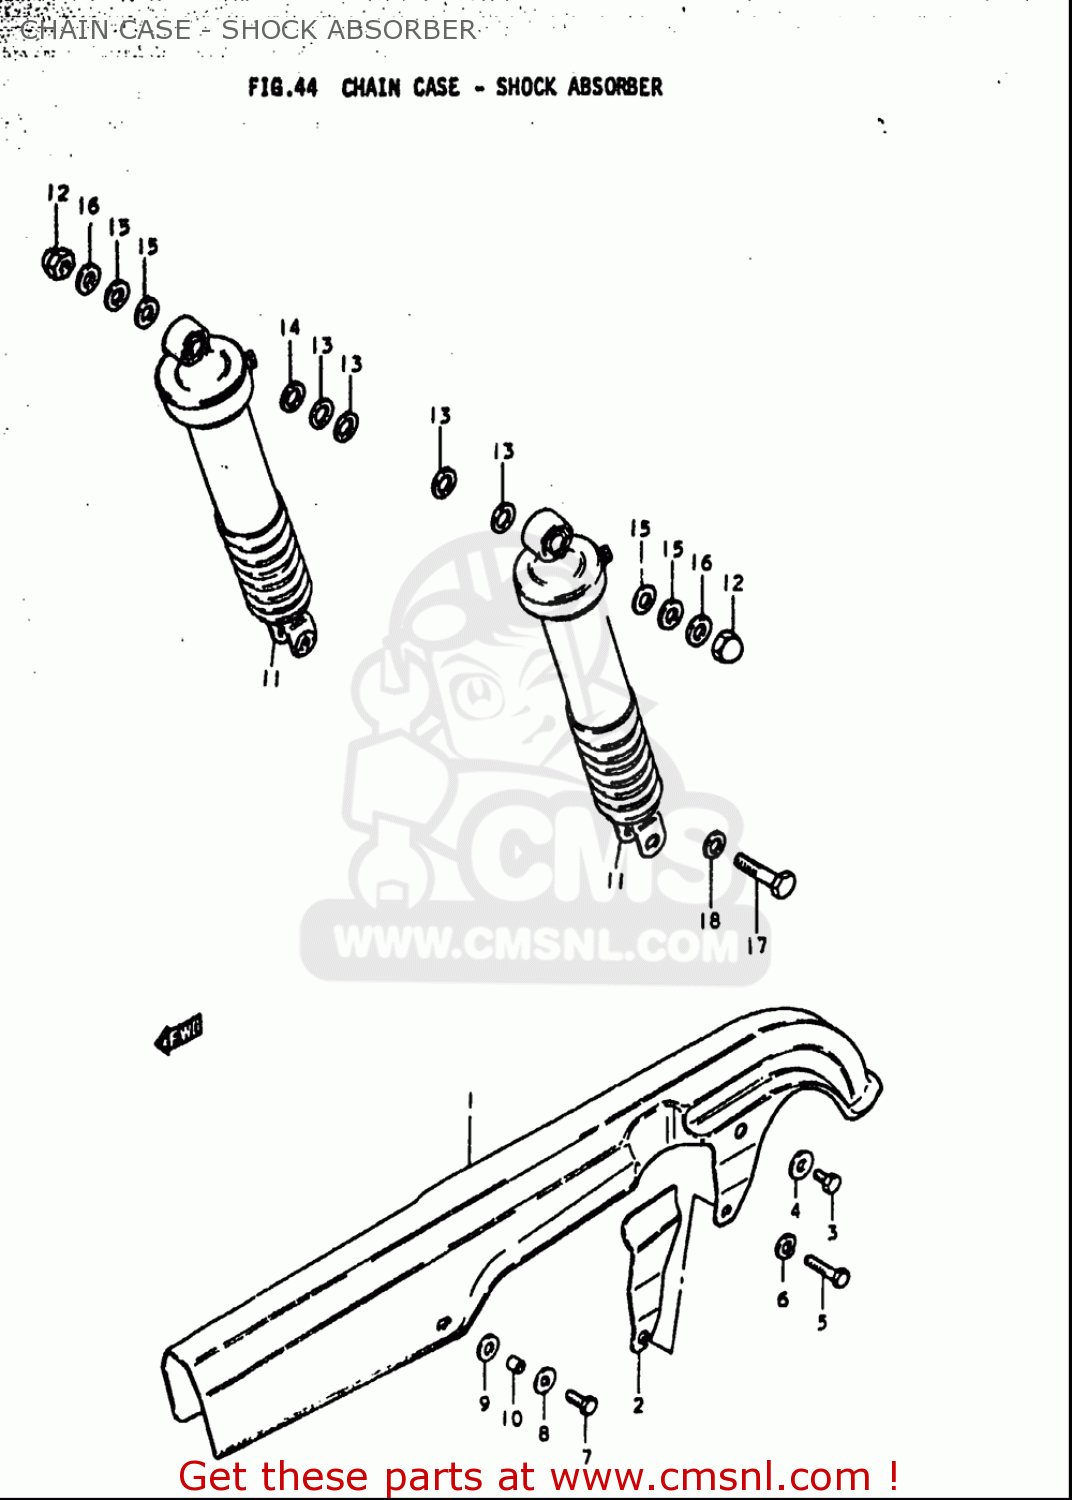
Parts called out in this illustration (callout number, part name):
1	CASE,CHAIN
2	REINFORCEMENT,CHAIN CASE
3	BOLT(6X8)
4	WASHER
5	BOLT
6	WASHER,LOCK
7	BOLT
8	WASHER(6.5X18X1)
9	WASHER(8X14X3)
10	SPACER(6.1X8X5.2)
12	NUT
13	WASHER
14	WASHER(12.5X24X3.2)
15	WASHER (10.5X24X2.3)
16	WASHER (10.5X25X3.2)
17	BOLT(10X36)
18	WASHER
